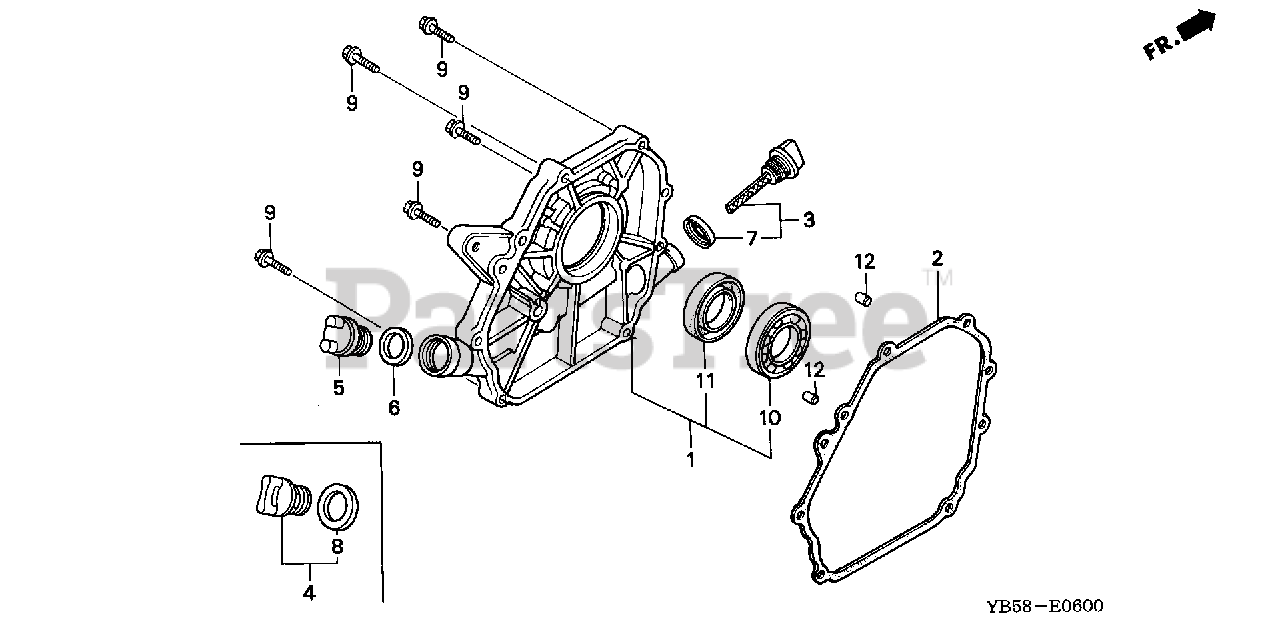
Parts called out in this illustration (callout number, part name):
1	COVER ASSY., CRANKCASE
2	GASKET, CASE COVER (NON-ASBESTOS)
3	CAP ASSY., OIL FILLER
4	CAP ASSY., OIL FILLER
7	GASKET, OIL FILLER CAP
8	GASKET, OIL FILLER CAP
9	BOLT, FLANGE (8X32)
10	BEARING, RADIAL BALL (6205)
11	OIL SEAL (25X41X6)
12	PIN, DOWEL (8X14)
